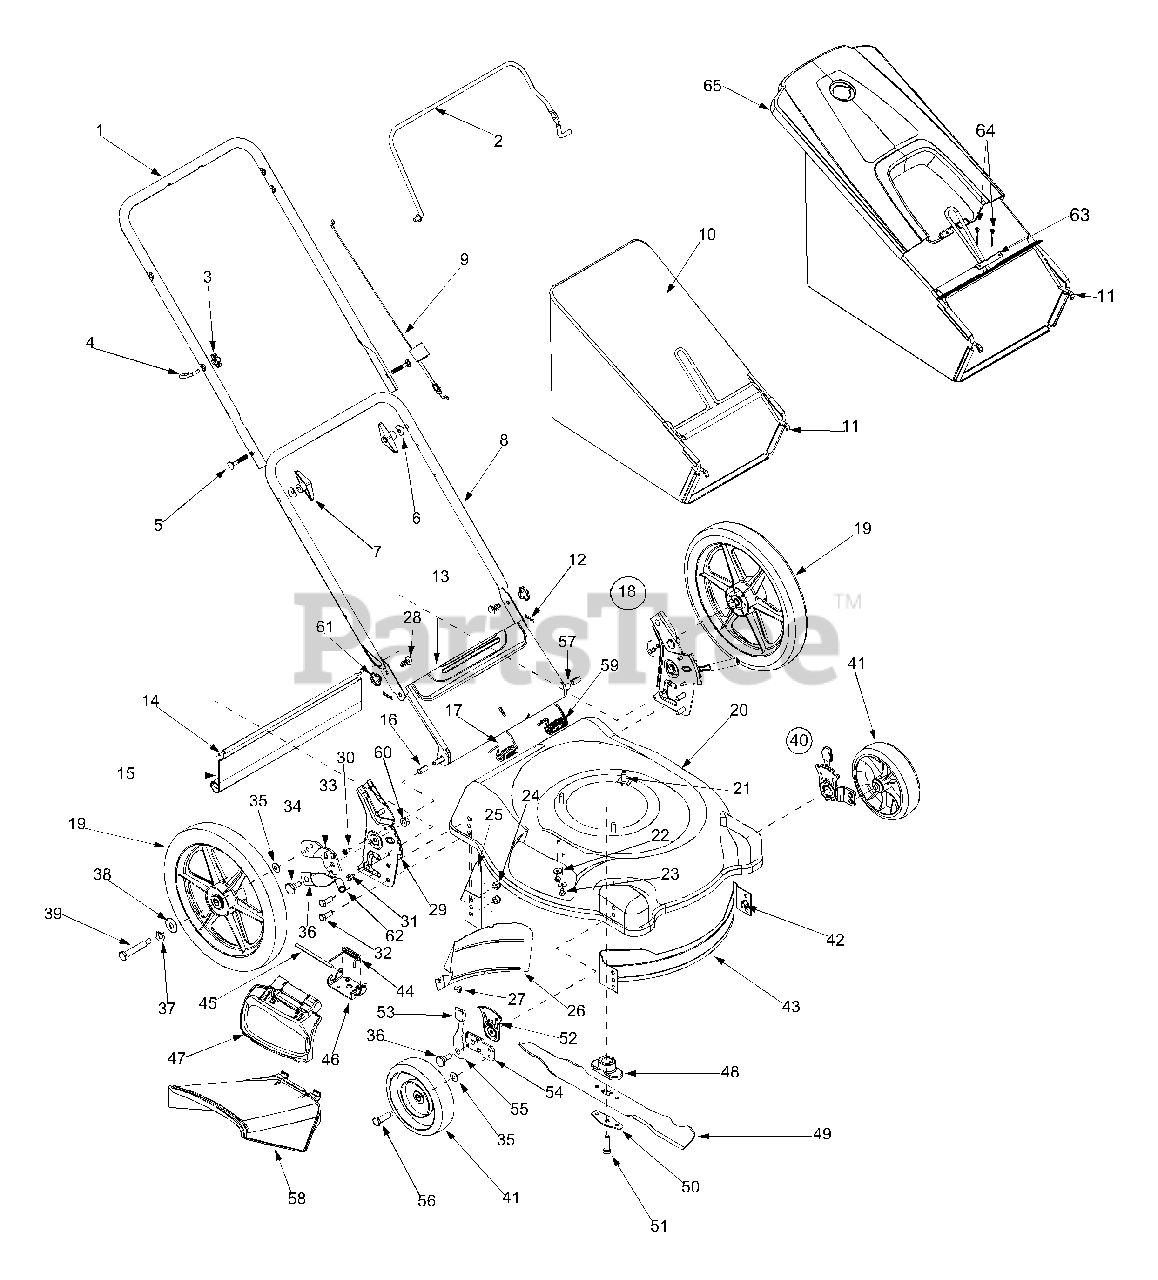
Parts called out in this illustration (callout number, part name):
3	Handle Knob
4	Rope Guide
5	Carriage Bolt 5/16-18 x 2"
6	Shoulder Washer.320 ID x.930 OD
7	Wing Nut
9	Control Cable
10	Grass Bag
12	Hairpin Clip
13	Grass Bag Door
14	Wire Rod
15	Trail shield
16	Spacer.390 O.D. x.810 I.D. x .950"
17	Door Spring-RH
18	Handle Brkt. w/Adj Ass'y Comp- LH
19	Rear Wheel Assembly 14 x 1.8
22	Bell Washer.265 ID x.75 OD
23	Hex Washer Screw 1/4-20 x.500
24	Hex Lock Nut 3/8-16
27	Tap Screw 1/4-14 x.625.
28	Hex Carriage Screw 1/4-20
29	Handle Bracket Assembly - RH
30	Machine Screw 1/4-20 x.500
31	Hex Washer Screw 1/4-14 x.625
32	Hex Cap Screw 3/8-16 x 1.0
33	Pivot Bar - RH
34	Shoulder Screw
35	Spring Washer.375 ID x.870 OD
36	Spring Lever
37	Wave Washer.500 ID x 1.0 OD
38	Flat Washer.510 ID x 1.37 OD
39	Shoulder Screw
40	Front Height Adjuster - RH
41	Front Wheel Assembly 7 x1.8
42	Flange Lock Nut 3/8-16
45	Hinge Pin
46	Hinge Mounting Bracket
47	Mulching Plug Ass'y Complete
48	Blade Adapter
49	21" Mulching
50	Blade Bell Support
51	Hex Cap Screw 3/8-24 x 1.5
52	Height Adjustment Plate
53	Height Adjustment Knob
55	Spring Lever
56	Shoulder Bolt
57	Chute Door Pivot Rod
58	Side Discharge Deflector
59	Door Spring - LH
60	Flange Lock Nut 3/8-16
61	Wing Nut
62	Foam Grip
65	Hard Top w/Logo and Indicator
